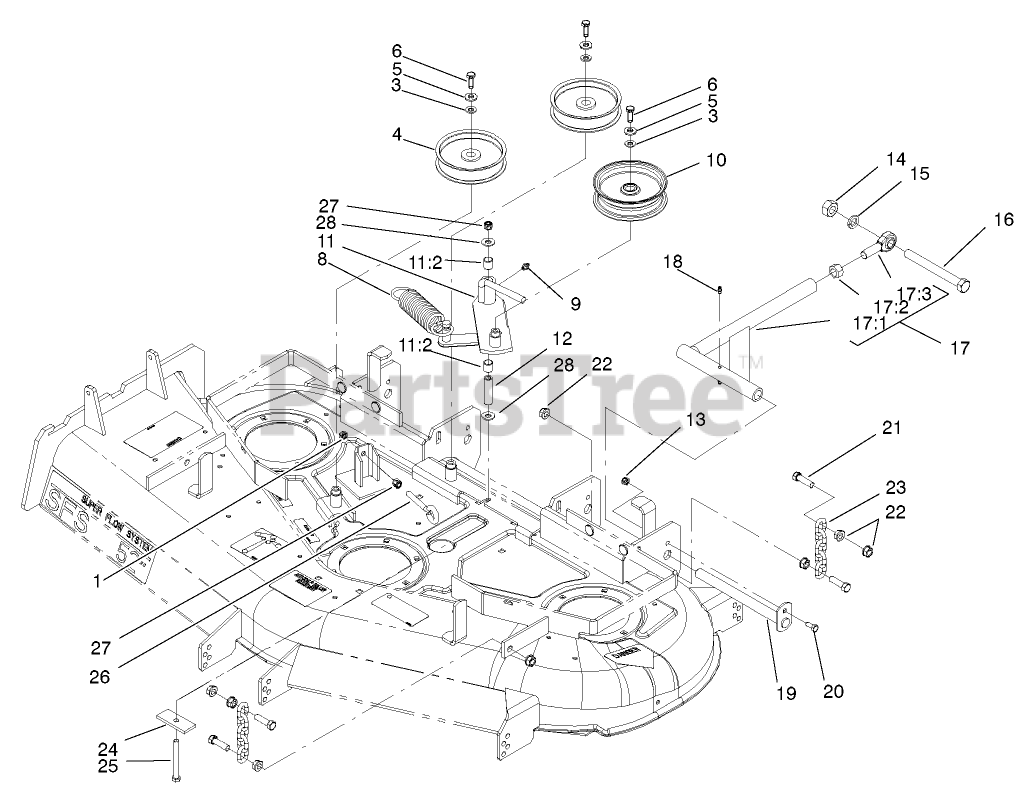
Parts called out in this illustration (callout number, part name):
1	NUT-HEX
3	WASHER-FLAT
4	PULLEY-IDLER
5	WASHER-BELLEVILLE
6	SCREW-HH
8	SPRING-EXTENSION
9	FITTING-GREASE, 90 DEG
10	PULLEY-IDLER
11	IDLER ARM ASM
11:2	SLEEVE-BEARING
12	BUSHING-PIVOT, IDLER
13	NUT-LOCK, NI
14	NUT-HEX
15	WASHER-LOCK
17	STRUT ASM
17:1	STRUT
17:2	NUT-HEX
17:3	BALLJOINT-SPHERICAL
18	FITTING-GREASE
19	PIN-STRUT
20	SCREW-HH
21	SCREW-CAP, HH
22	NUT-HF
23	CHAIN-LIFT, DECK
24	PLATE-RETAINER, BOLT
25	SCREW-HH
26	BOLT-EYE
27	NUT-LOCK, NI
28	WASHER-HARDENED
